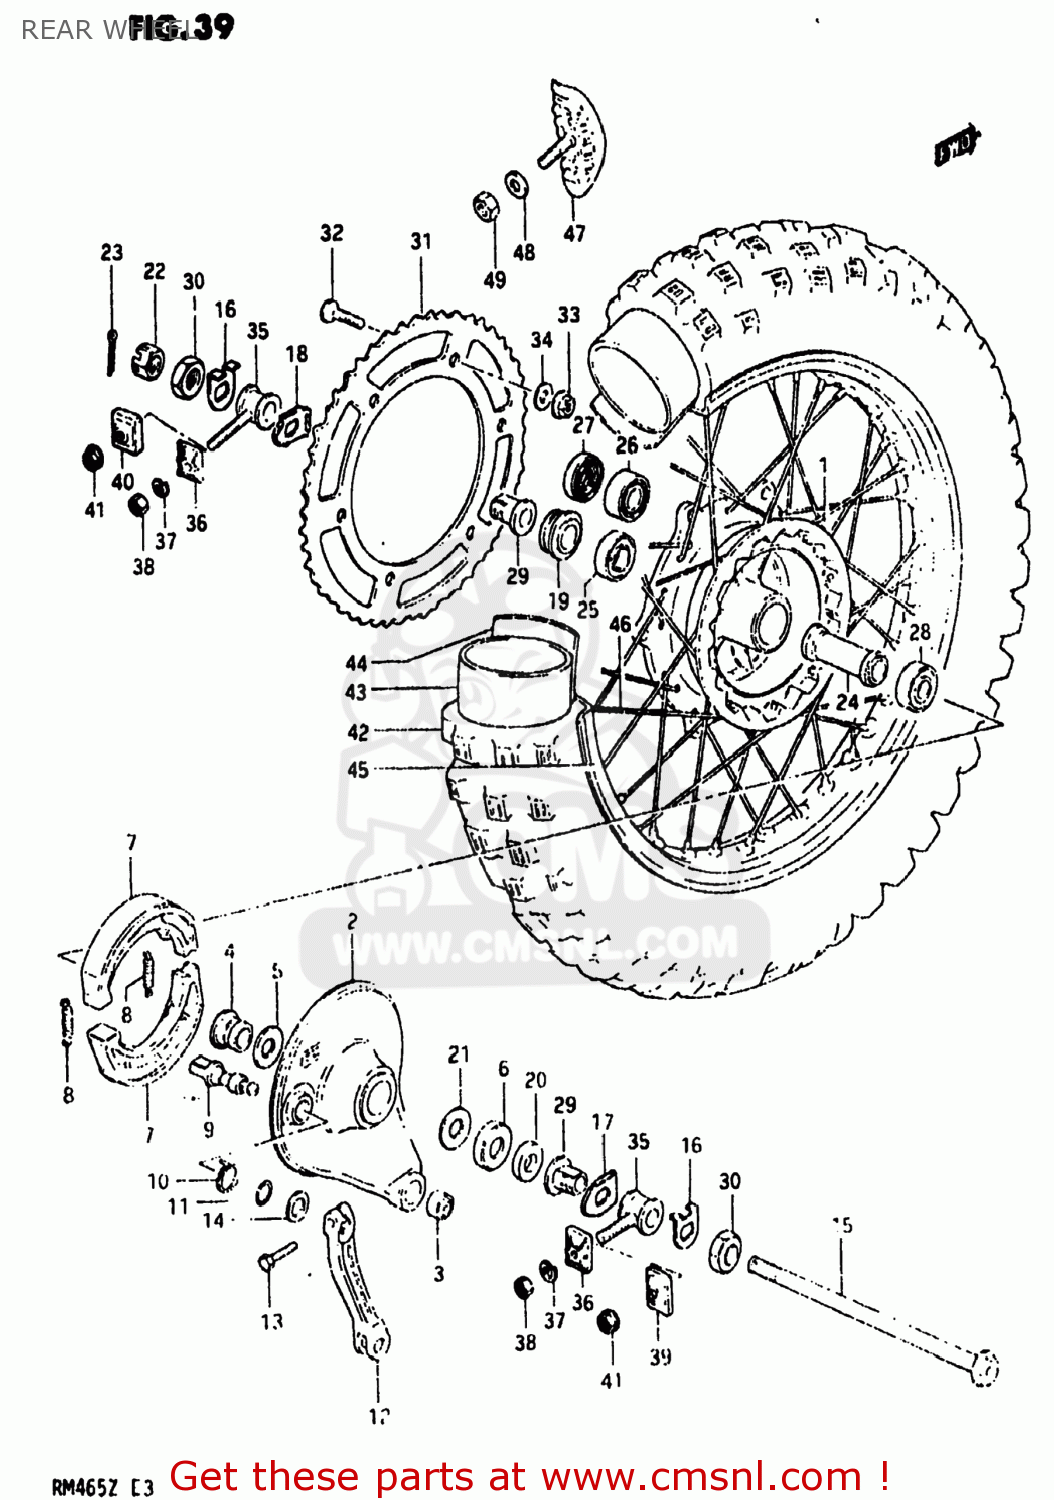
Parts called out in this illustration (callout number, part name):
1	DRUM,REAR HUB
2	PANEL SET,REAR HUB
3	SPHERICAL BRNG,TORQUE LINK
4	SPACER,RR BRAKE ANCHOR PANEL
5	SEAL,OIL(20X27X5)
6	CVR,RR BRAKE AHR PNL DUST SEAL
7	SHOE,BRAKE
8	SPRING
9	CAM,FR BRAKE
10	SPRING
11	O RING(D:2.5,ID:11.4)
12	LEVER,RR BRAKE CAM
13	BOLT
14	WASHER(12.5X20X1)
15	AXLE,REAR
16	WASHER,CHAIN ADJUSTER
17	PLATE,CHAIN ADJUSTER,RIGHT
18	PLATE,CHAIN ADJUSTER,LEFT
19	SPACER,REAR AXLE,LEFT
20	SPACER,REAR AXLE,RIGHT
21	WASHER,THRUST
22	NUT
23	COTTER PIN
24	SPACER,REAR HUB BEARING
25	BEARING
26	BALL BEARING 15X35X16
27	OIL SEAL
28	BEARING
29	SPACER,CHAIN ADJUSTER
30	NUT
31	SPROCKET,REAR
32	SCREW
33	NUT
34	WASHER
35	ADJUSTER,CHAIN
36	PLATE,CHAIN ADJUSTER GEAR
37	LOCK WASHER
38	NUT
39	PLATE,CHAIN ADJUSTER GEAR
40	PLATE,CHAIN ADJUSTER GEAR
41	NUT
42	TIRE
43	TUBE,INNER
44	PROTECTOR,WHEEL,INNER
45	RIM,REAR WHEEL
46	SPOKE SET,REAR WHEEL
47	STOPPER,BEAD
48	WASHER
49	NUT
